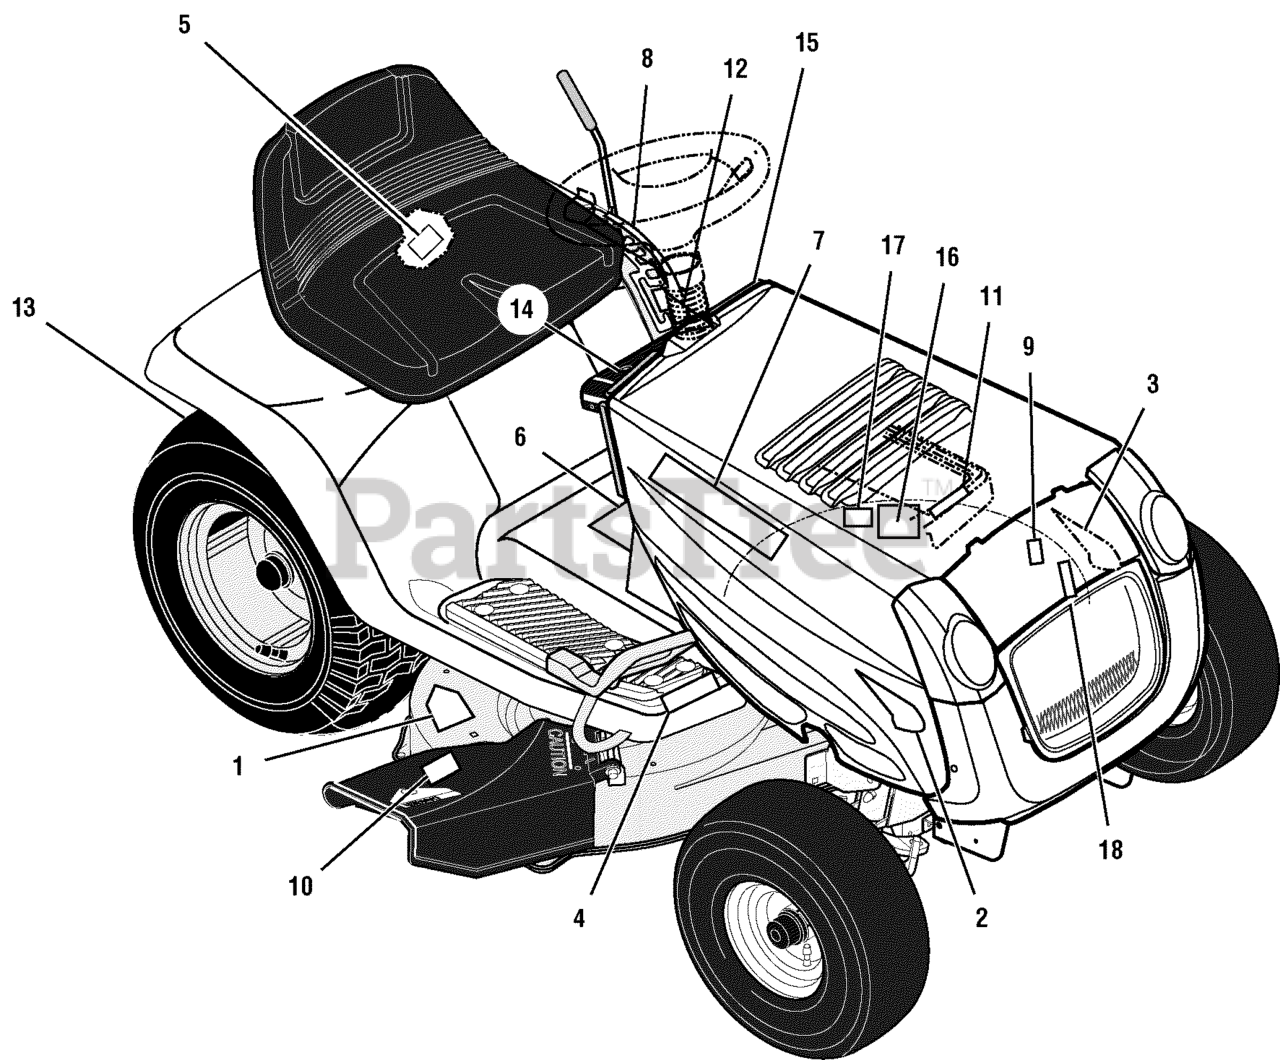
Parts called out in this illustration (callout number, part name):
1	DECAL, ENGLISH CUT FINGER
2	DECAL, 17/42 RH
3	DECAL, 17/42 LH
4	DECAL, V3-DC-5X2 HYDRO DRIVE
5	DECAL, HYDRO RELEASE DOM
6	DECAL, WARNING
7	DECAL, SENTINEL BY MUR R & L
8	DECAL, 1/6 HGT ADJUST LIFT LGSD
9	DECAL, NO STEP LH HSNG
10	DECAL, NO STEP CHUTE
11	DECAL, BRAKE/PARK BRAKE
12	DECAL, DECK LEVEL POS/ONLY
13	DECAL, DRAWBAR WARNING PICT
14	DECAL, IGNITION ENGAGE PRK BRK (NMR)
15	DECAL, THROTTLE SNGLE W/CHOKE
16	DECAL, GAGE WHEEL INST
17	DECAL, GAGE WHEEL LEVELING
18	DECAL, 3 WAY
